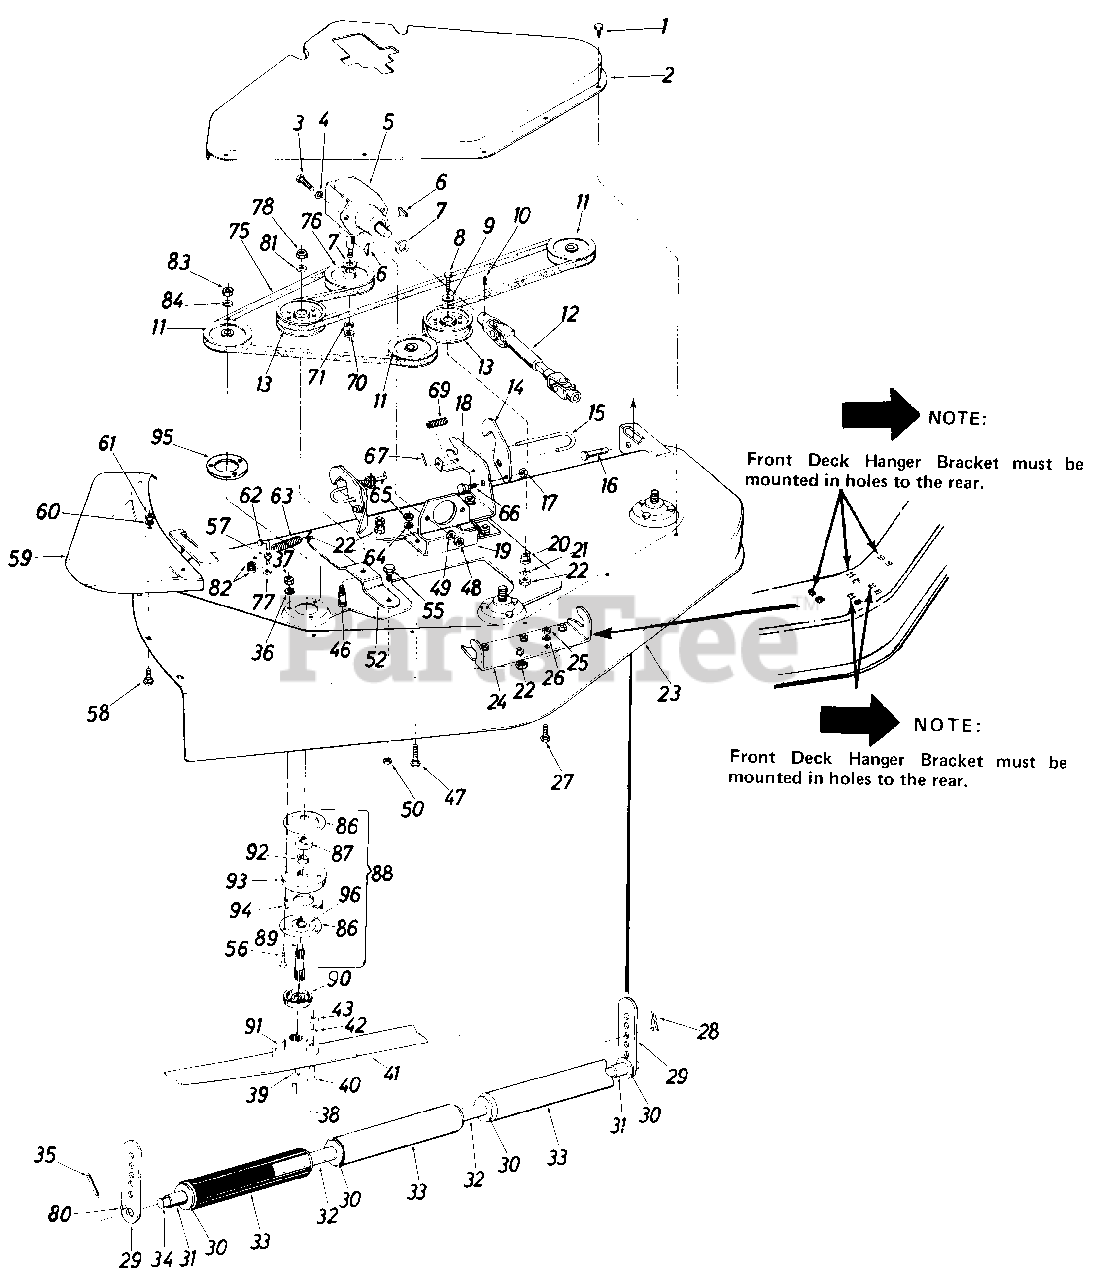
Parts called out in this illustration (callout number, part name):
1	Hex B Tap Scr. 1/4-20 x .38" Lg.
4	Ext. L-Wash. 3/8" Scr.*
5	Right Angle rive
6	#9 Hi-Pro Key 3/16 x 3/4" D ia.
7	Fl-Wash. 29/32 I.D.
8	Hex Scr 3/8-16 x 1.25" Lg.*
9	Fl Wash 3/8" I.D.
10	Sq. Hd. Set Scr. 3/8-16 x .50" Lg. Cup
11	Deck Pulley
12	Universal Drive Shaft Ass'y.
13	Deck Idler Pulley
14	Hanger Lock
15	Release Pin
16	Clevis Pin .500 Dia.
17	Hex Cent. L-Nut 5/16-1 8 Thd.
21	L-Wash. 3/8" Scr.*
22	Hex Nut 3/8-16" Thd.*
26	L-Wash. 5/16" Scr.*
27	Carriage Bolt 5/16-18 x 1.00" Lg.*
28	Internal Cotter Pin
30	Fl-Wash. .75 I.D. x 1.5 O.D.
31	Spacer .758 I.D. x 1.25 O.D. x . 530
34	Roller Shaft
35	Roll Pin 3/16 x 1.25
36	L-Wash. 5/16" Scr.*
37	Hex Cent. L-Nut 5/16-24 Thd.
38	Hex Scr. 3/8-24 x .75" Lg. Thd. Rolling
39	L-Wash. 3/8" Scr. H.D.
40	Hex Scr. 5/16-24 x 1.00" Lg.
41	Blade 17"
42	L-Wash. 5/16" Scr.*
43	HexCent. L-Nut5/16-2 Thd.
46	Hex Scr. 5/8-18 x 1.31" Lg.
47	Carriage Bolt 5/16-18 x .75"
48	Hex Nut 3/8-16 Thd.*
49	L-Wash. 3/8" Scr.*
50	Hex Cent. L-Nut 7/16-14
56	Hex Scr. 5/16-24 x 1.50" Lg. (Grade 5)
57	Hex Nut 1/4-2 Thd.*
58	Carriage Bolt 5/16-18 x .75 Lg.*
60	L-Wash. 5/16" Scr.*
61	Hex Nut 5/16-18 Thd.*
62	Hook Bolt
63	Extension Spring
64	L-Wash. 5/16" Scr.
65	Hex Nut 5/16-18 Thd.*
66	Shld. Scr.
67	Roll Pin 1/8" Dia.
69	Compression Spring
70	HexCent. L-Nut5/8-18 Thd.
71	L-Wash. 5/8" Scr.*
75	" V"-Belt
76	Drive Pulley
77	HexCent. L-Nut 1/4-2 Thd.
78	Hex Cent. L-Jam Nut 5/8-18 Thd.
80	Spring Pin Spiral 1/4" Dia. 1.00" Lg.
81	Fl-Wash..62" I.D.
82	Ext. L-Wash. 1/4" Scr.*
83	Hex Jam Nut 5/8-18 Thd.
84	L-Wash. 5/8" I.D.*
86	Bearing Housing
87	Ball Bearing
88	Deck Spindle Ass'y.
89	Spindle
90	Bearing Shield
91	Blade Adapter
92	Spacer
93	Spindle Spacer Plate
94	Reinforcement Plate
95	Spindle Reinforcement Plate
96	Open Bearing Housing
